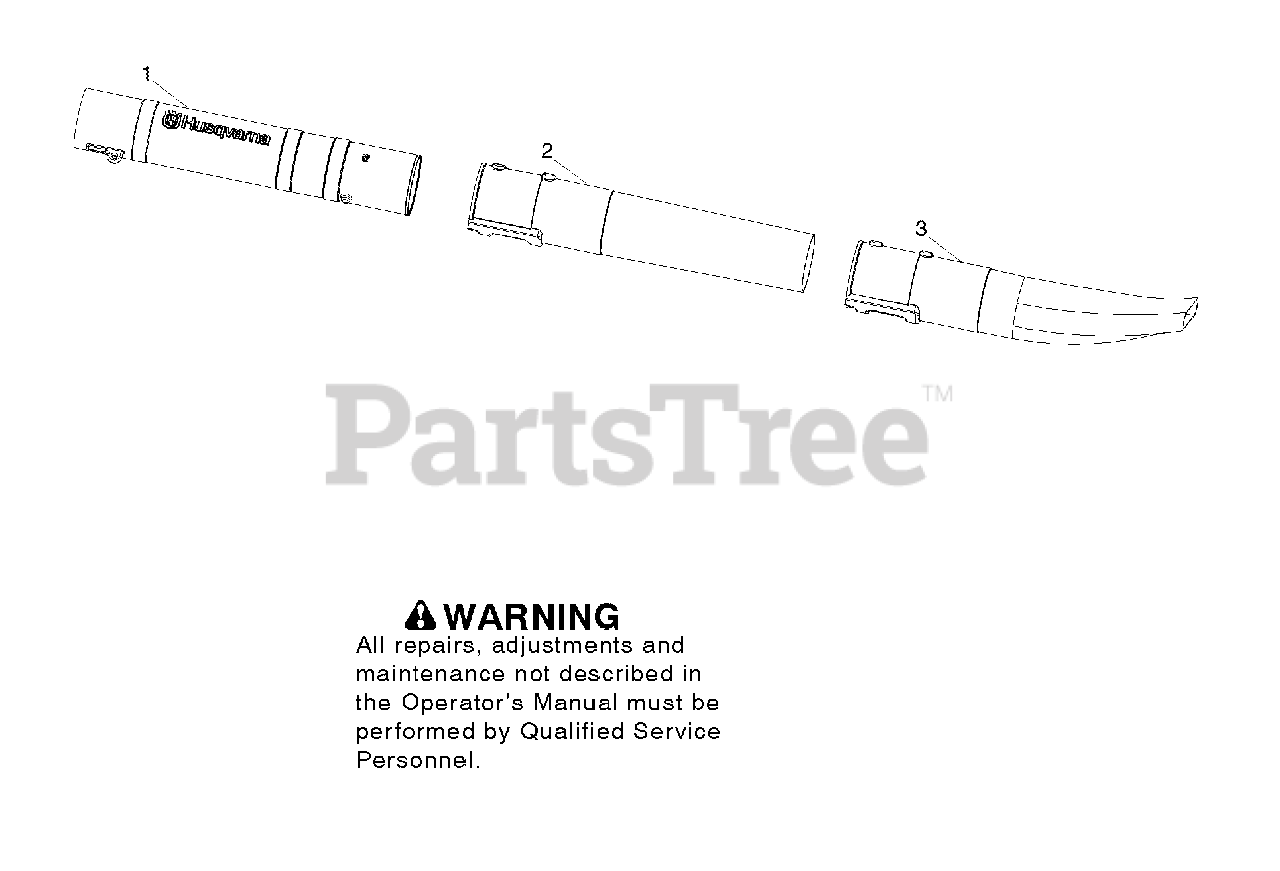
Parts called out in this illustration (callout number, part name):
1	Assy - Tube - Upper Blower w/barrier
2	Tube - Lower blower
3	Tube - Lower blower
